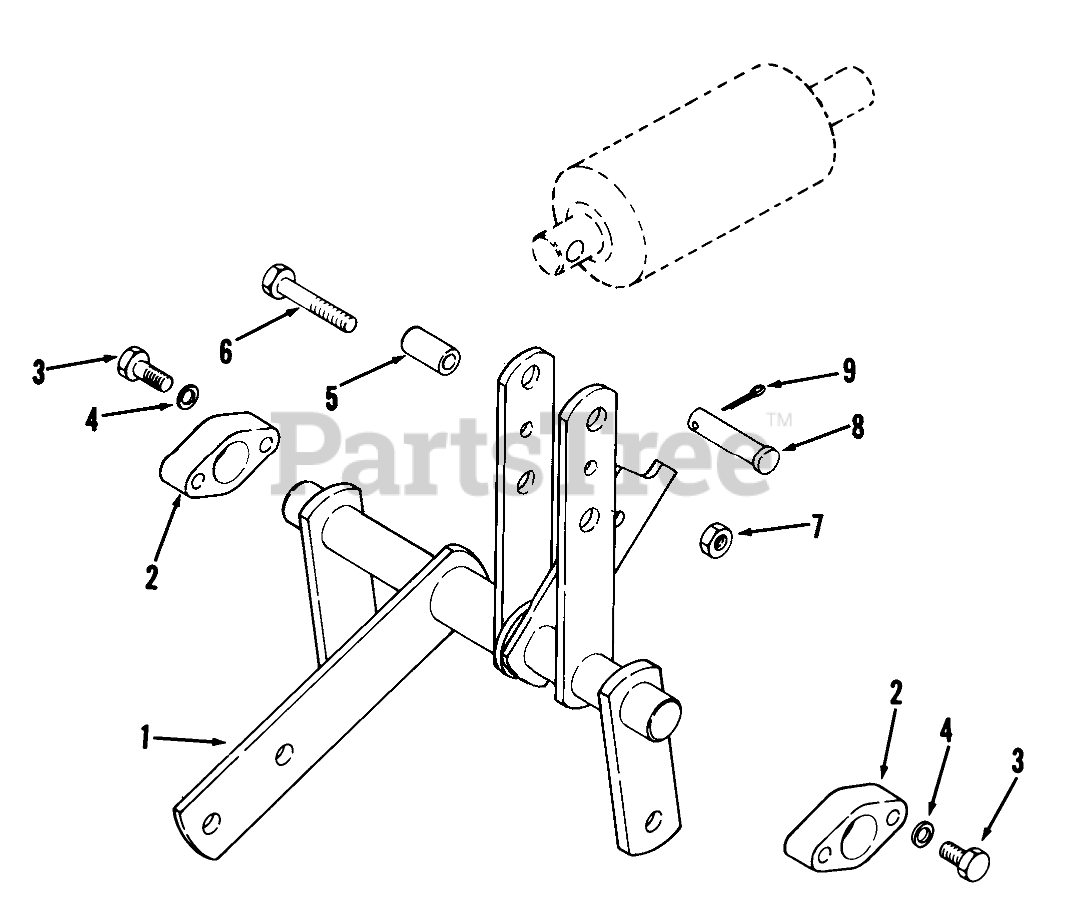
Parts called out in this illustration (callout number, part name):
1	Assy-Lift Bellcrank
2	BLOCK R
3	BOLT
4	LOCKWASHER
5	Spacer
6	Bolt
7	NUT
8	PIN CLEVIS .50 DIA
